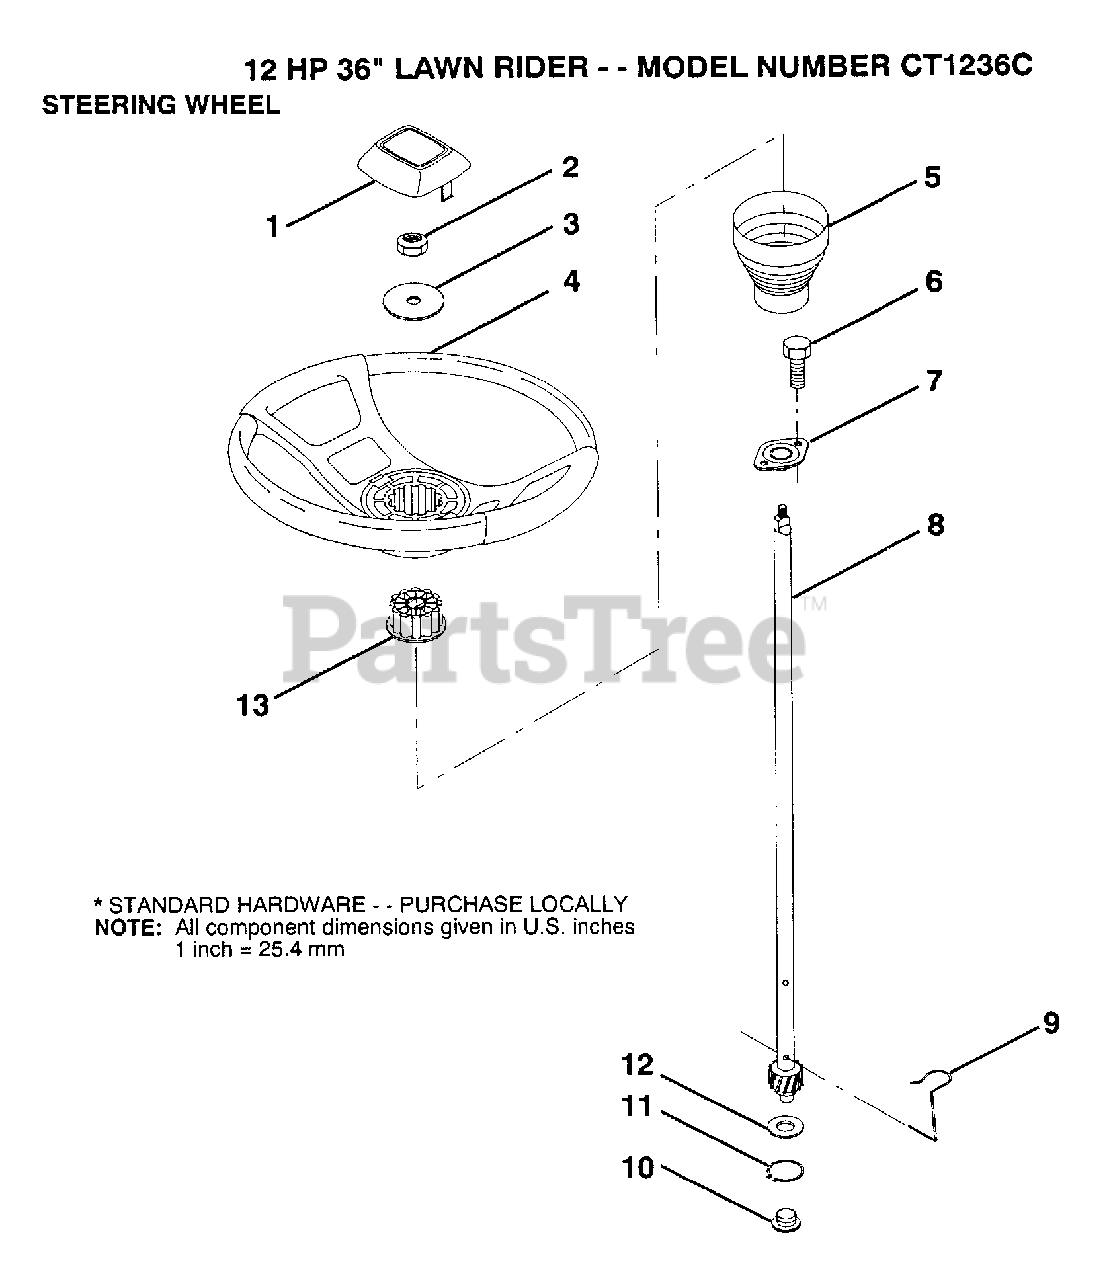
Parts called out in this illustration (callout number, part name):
1	INSERT-WHEEL LT
2	GRIPCO NUT
3	WASHER T
5	SLEEVE STEERING
9	STEERING CLIP
10	BUSHING STEER LWR
11	RING
12	WASHER LT
13	ADAPTER-WHEEL LT
